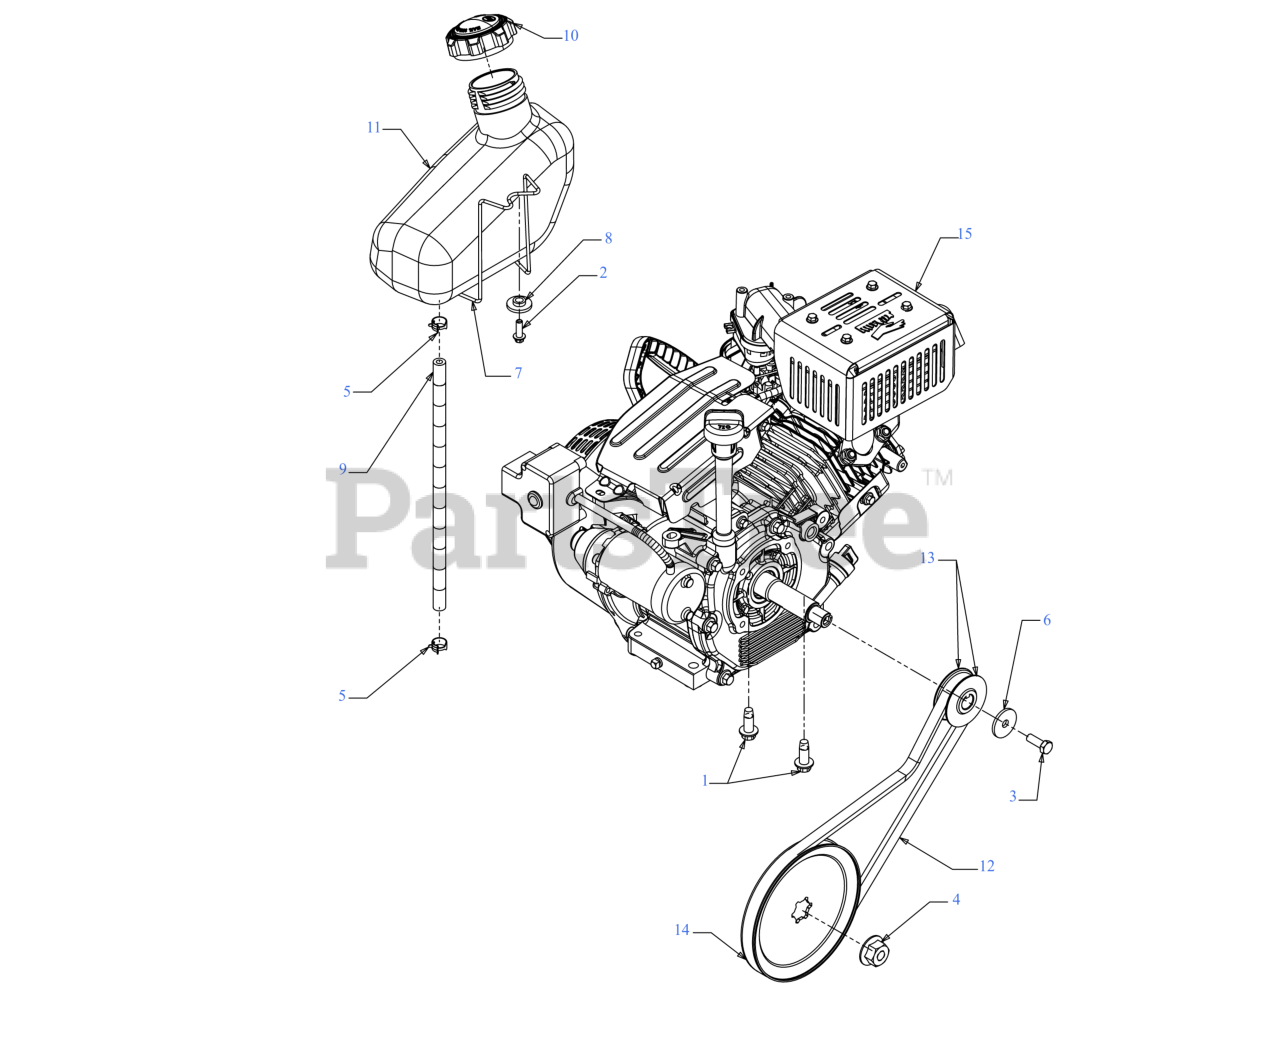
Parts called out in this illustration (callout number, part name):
1	SCREW 3/8-16 x 1
2	SCREW 1/4 x .750
3	SCREW 5/16-24 x .875 GR5
4	FLANGE NUT W/HUB
5	HOSE CLAMP 1/20
6	WASHER-5/16 x 1.25X 1.27
7	FUEL TANK WIRE SUPPORT
8	SHOULDER SPACER
9	FUEL HOSE LOW PERMEATION
10	FUEL CAP
11	FUEL TANK
12	V-BELT .500 x 35.00LG
12	Cub Cadet AUGER BELT
12	Genuine Factory Parts AUGER BELT
13	HALF PULLEY
14	AUGER PULLEY
15	COMPLETE ENGINE
